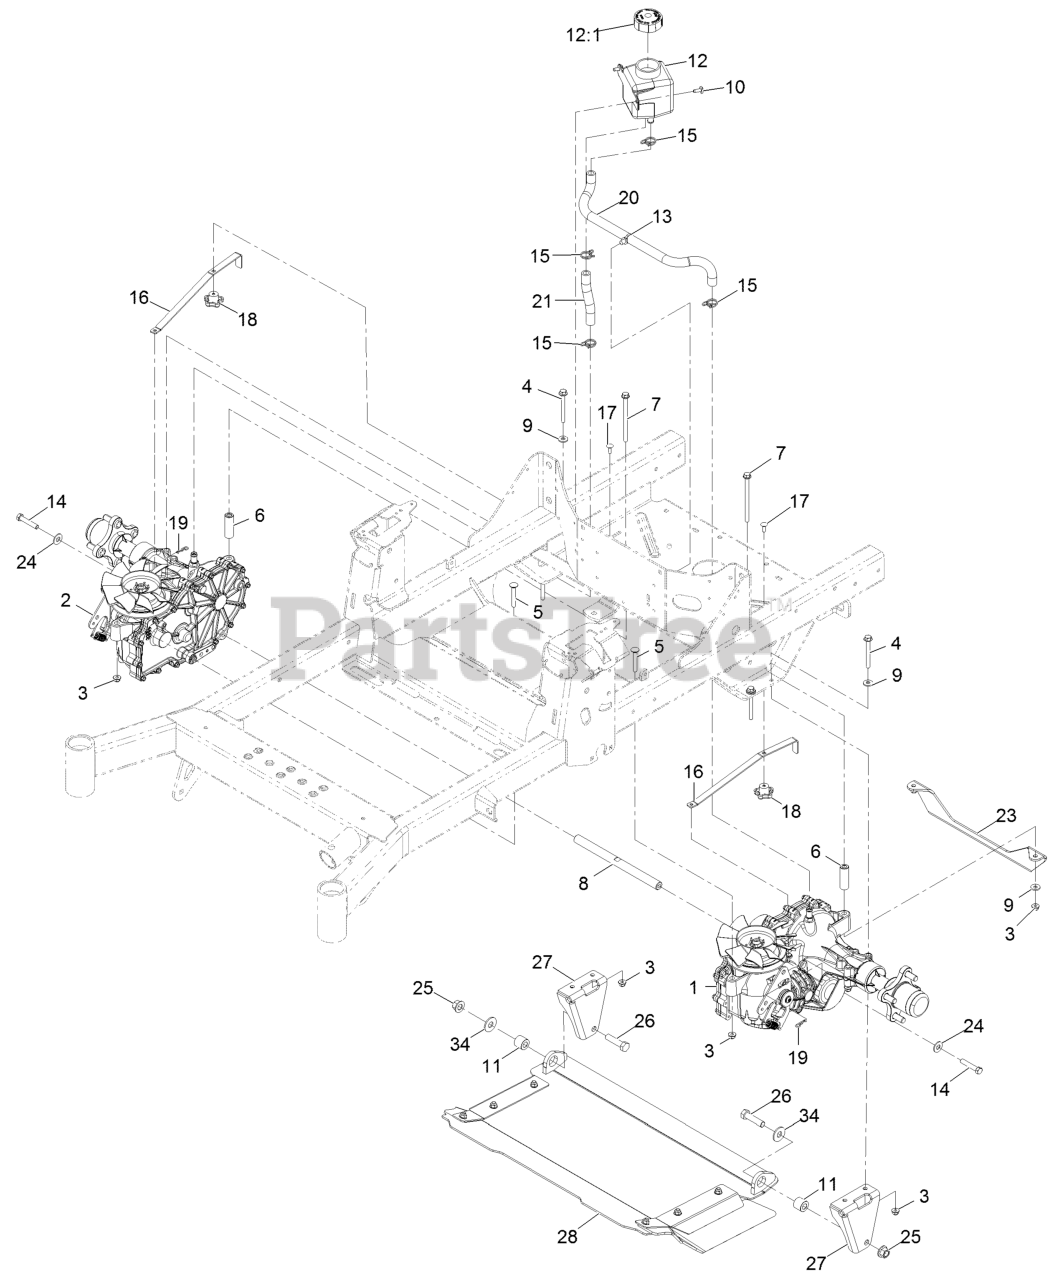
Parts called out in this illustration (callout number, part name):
1	LH TRANSAXLE ASM
2	RH TRANSAXLE ASM
3	NUT-HF, NI
4	SCREW-HHF
5	BOLT-CARR
6	SPACER-HYDRO
7	SCREW HHF
8	SHAFT-SPACER
9	WASHER-SPRING
10	SCREW-TORX
11	BUSHING-SLEEVE
12	TANK-HYD
12:1	CAP-RESERVOIR, HYD
13	CLIP-TIE
14	SCREW-HH W/LOCTITE
15	CLAMP-HOSE
16	ARM-BYPASS, HYDRO
17	BOLT-CARR
18	KNOB-HANDLE
19	PIN-COTTER
20	HOSE-HYDRAULIC
21	HOSE-HYDRAULIC
23	SUPPORT-TRANSMISSION
24	WASHER-FLAT
25	Nut-Lock 1/2-13
26	SCREW-HH
27	BRACKET-MOUNT, DISCHARGE
28	DISCHARGE TUNNEL ASM
34	WASHER-FLAT
